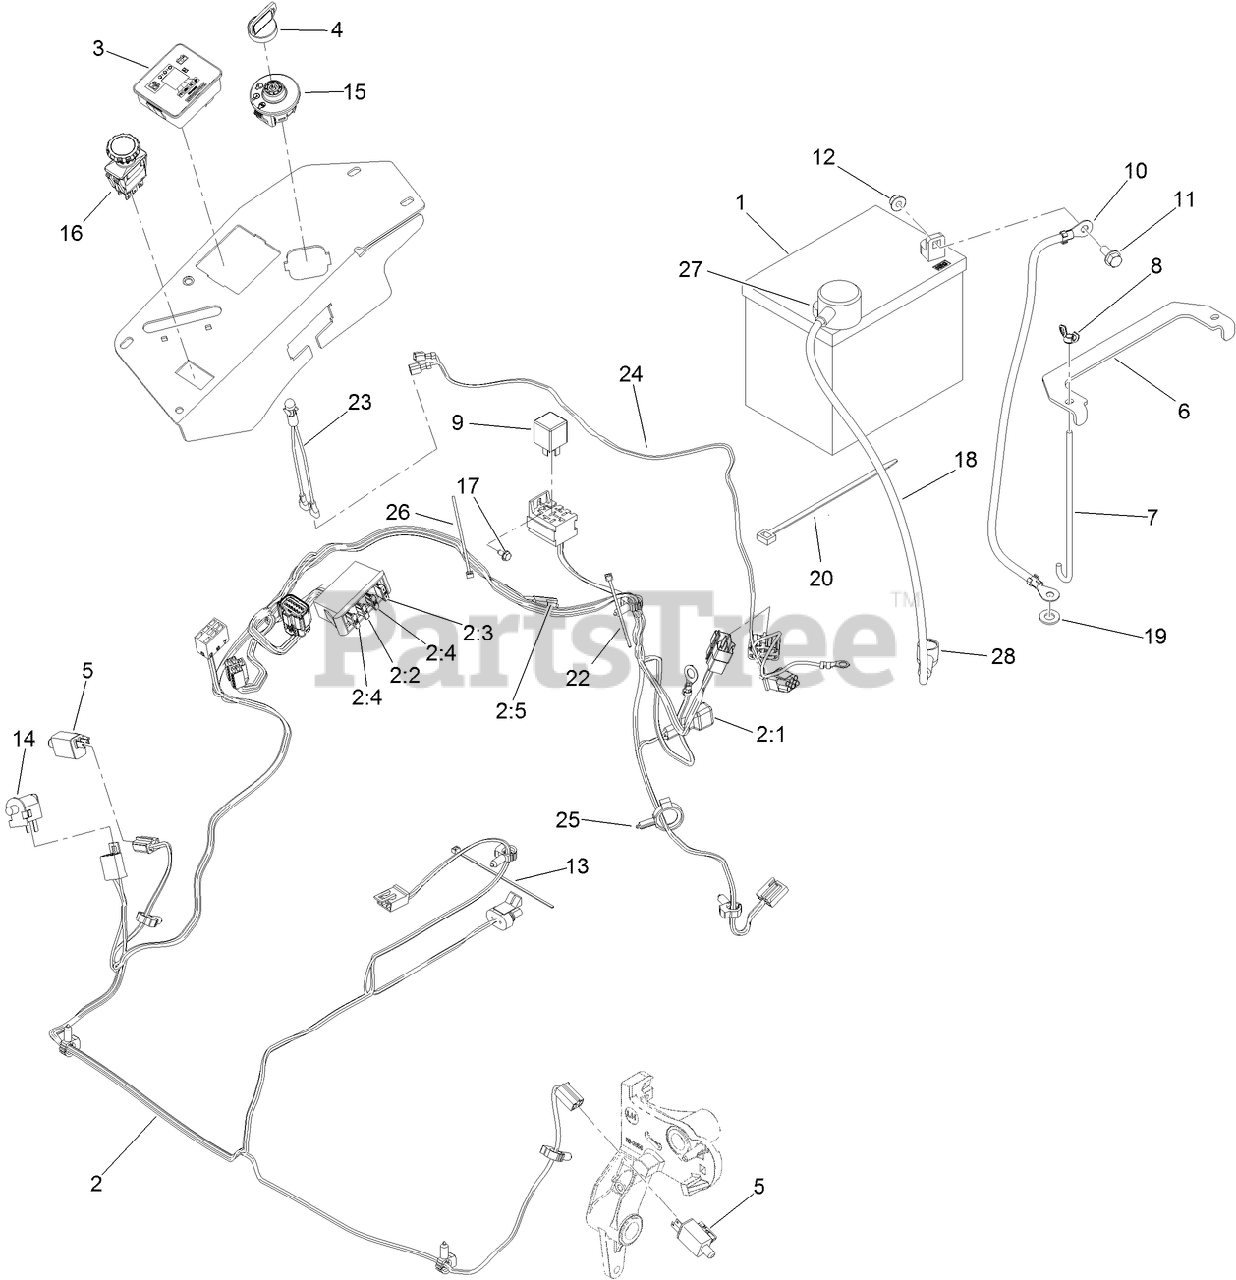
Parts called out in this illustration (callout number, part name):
1	BATTERY-DRY
1	BATTERY (300 CCA, WET)
2	HARNESS-WIRE, MAIN
2:2	FUSE-BLADE, 10 AMP
2:3	FUSE-BLADE, 15 AMP
2:4	FUSE-BLADE, 25 AMP
2:5	CAP-PLUG
3	FUEL/HOUR METER ASM
4	KEY-IGNITION
5	SWITCH
6	STRAP-TIE DOWN, BATTERY
7	BOLT-HOLDDOWN
8	WINGNUT
10	CABLE-BATTERY, NEGATIVE
11	SCREW-HHF
12	NUT-HF, NI
13	TIE-CABLE
14	SWITCH-BAIL
15	SWITCH-IGNITION
16	SWITCH-PTO, 10 AMP
17	SCREW-HWH
18	CABLE-BATTERY, POSITIVE
19	WASHER-FLAT
20	TIE-PLASTIC
22	TIE-PLASTIC
23	INDICATOR-LED, RED
24	HARNESS-LIGHT, INDICATOR
25	CLAMP-HOSE
26	TIE-CABLE
27	INSULATOR-BATTERY
28	INSULATOR-SOLENOID
